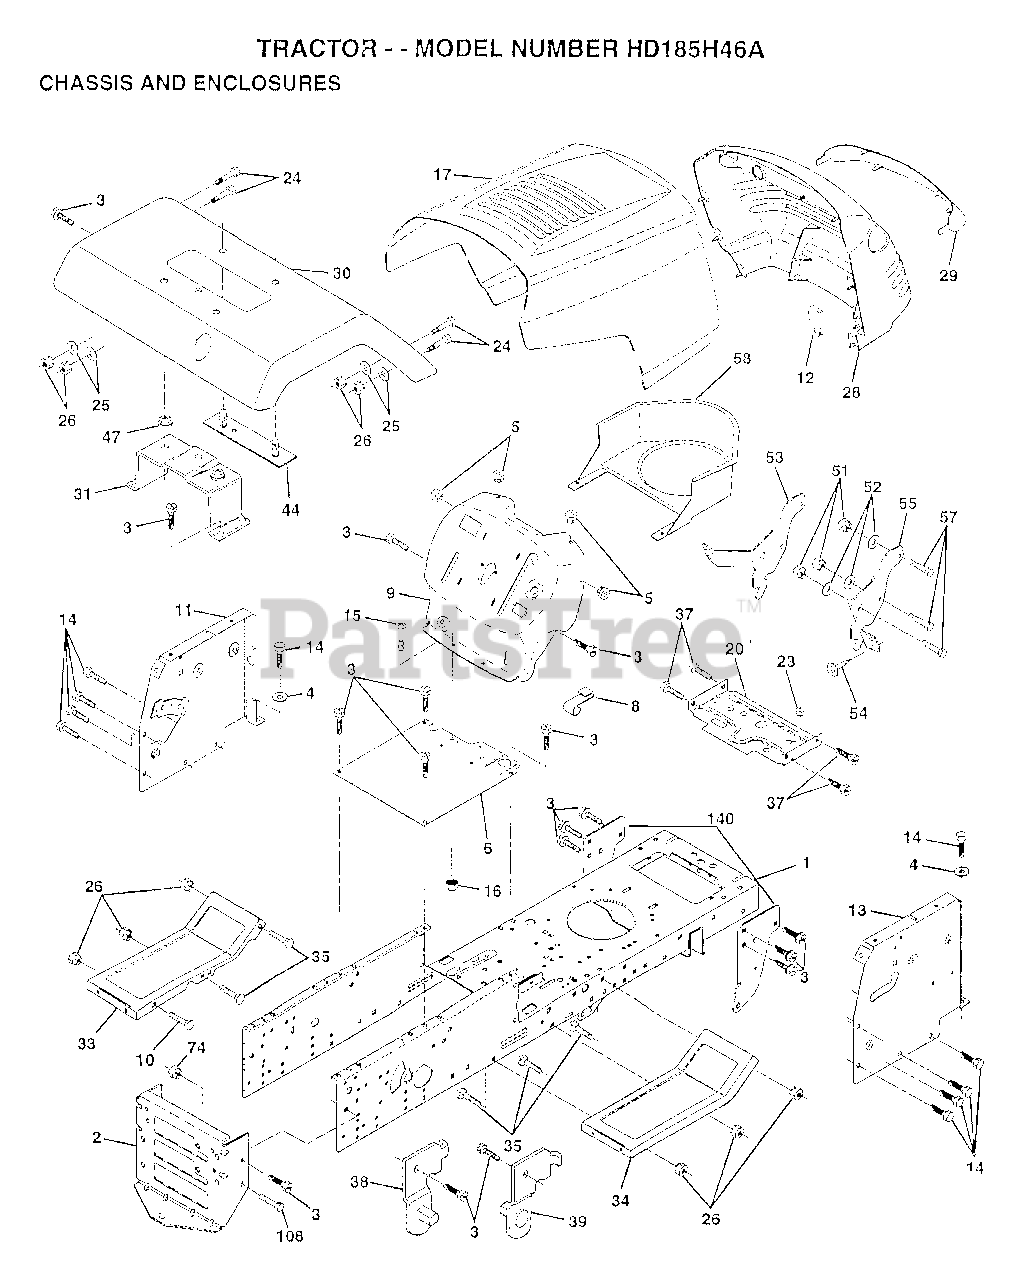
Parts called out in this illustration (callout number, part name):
1	CHASSIS ASM
3	SCREW
4	WASHER
5	BUMPER-HOOD/DASH
6	SADDLE
8	"CLIP,INSULATOR"
9	DASH SILKSCREEN
11	PANEL ASM DASH LH
12	CLIP.TINNERMAN
13	PANEL DASH RH
14	SCREW LT
15	SCREW
20	"PLATE-MTG,BATT/FU"
24	BOLT
25	WASHER
26	NUT
28	GRILLE-MS428
29	LENS GRILLE
30	"FENDER WS,FTK"
31	BRKT.ASM.FENDER
33	FOOTREST PNT LH
34	FOOTREST.RH.LT/GT
35	BOLT
37	SCREW LT
38	BRACKET ASM LH
39	BRACKET ASM RH
44	STRAP ASM FENDER
47	NUT-PUSH YT
51	NUT
52	WASHER
53	BRACKET.GRILLE.LH
55	BRACKET.GRILLE.RH
58	DUCT.AIR.B&S.18HP
140	BRKT SUSPENSION
